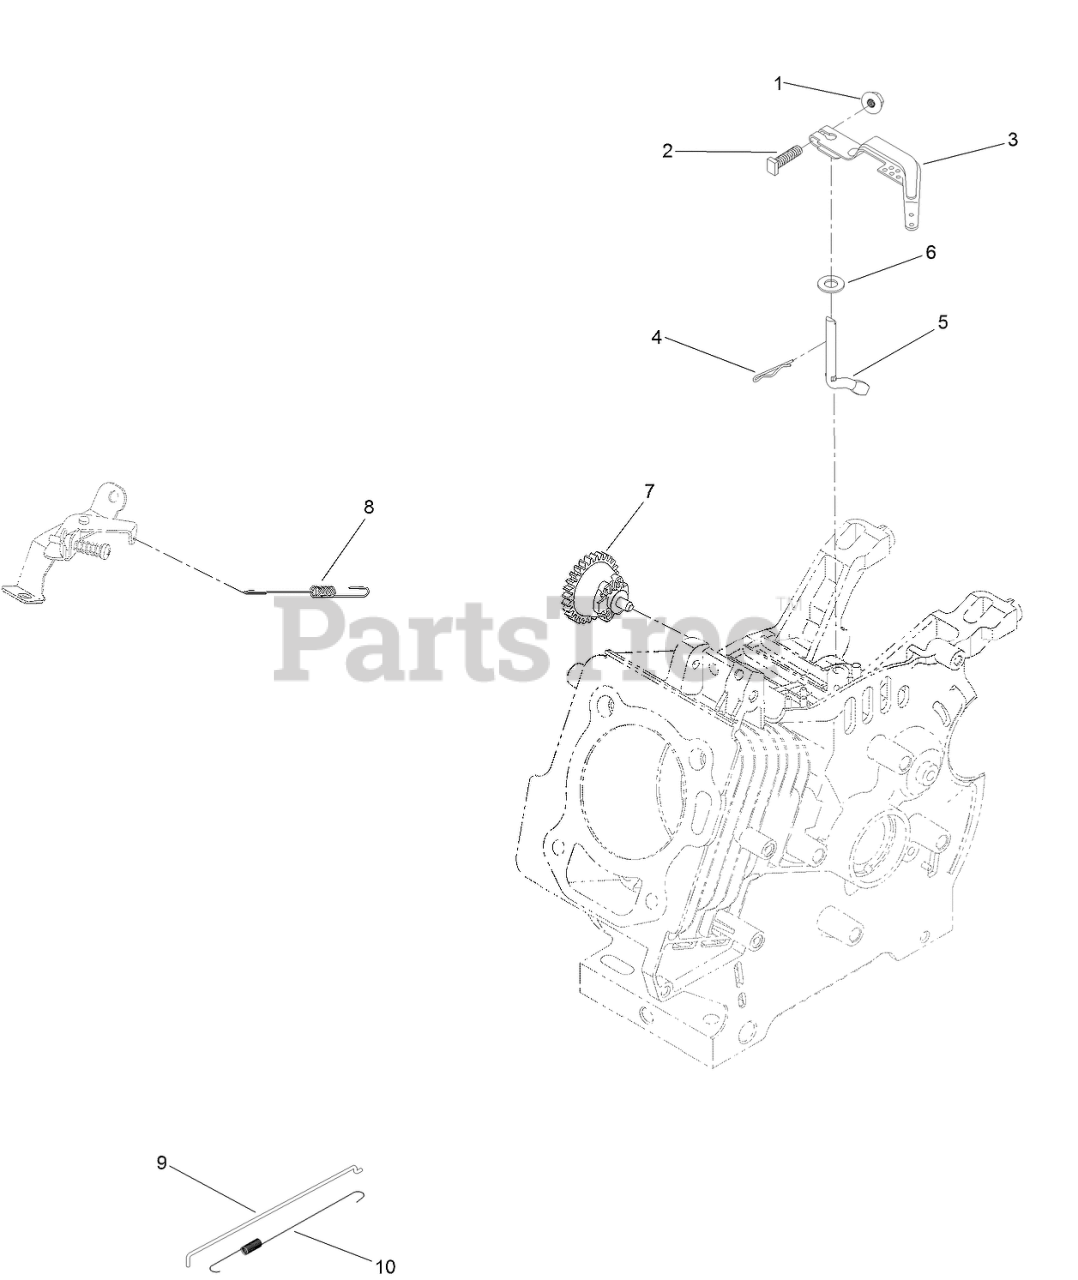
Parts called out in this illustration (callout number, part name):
1	NUT-FLANGE
2	BOLT-ARM, GOVERNOR
3	ARM-GOVERNOR
4	PIN-HAIR
5	SHAFT-GOVERNOR
6	WASHER-PLAIN
7	GOVERNOR GEAR ASM
8	SPRING-GOVERNOR
9	ROD-GOVERNOR
10	SPRING-RETURN, THROTTLE
